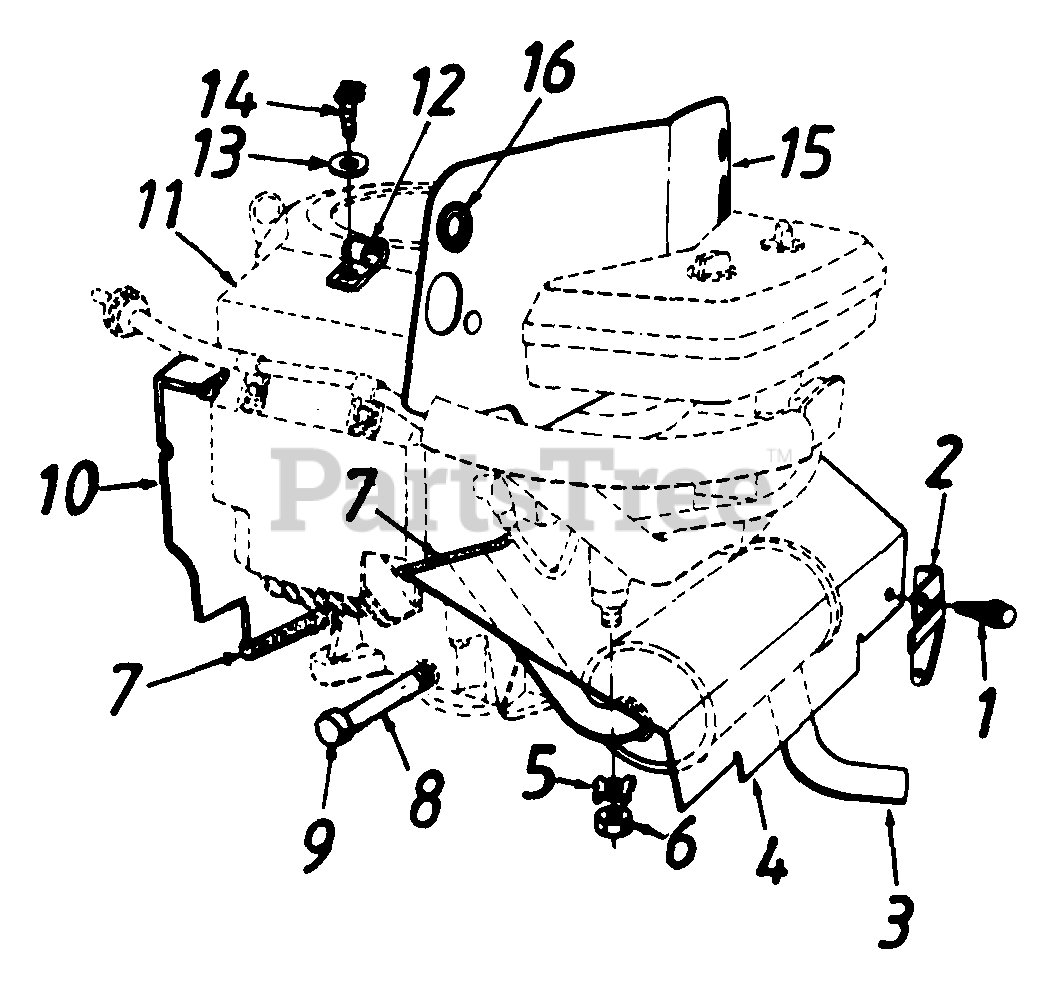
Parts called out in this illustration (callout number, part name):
1	Hex AB-Tap Scr. 1/4 x .62"
3	Muffler
4	Front Heat Shield
5	Spec. L-Wash. 5/16 x .88"
6	Hex Nut 5/16-18 Thd.
7	Trim Strip 12" Lg.
8	Pipe Nipple
9	Oil Drain Cap
10	Rear Baffle
11	Engine
12	Clamp
13	Fl-Wash..188" I.D. x.438"
14	Truss Mach. AB-Tap Scr. #10 x .5" Lg.
15	Heat Shield
16	Rubber Grommet
